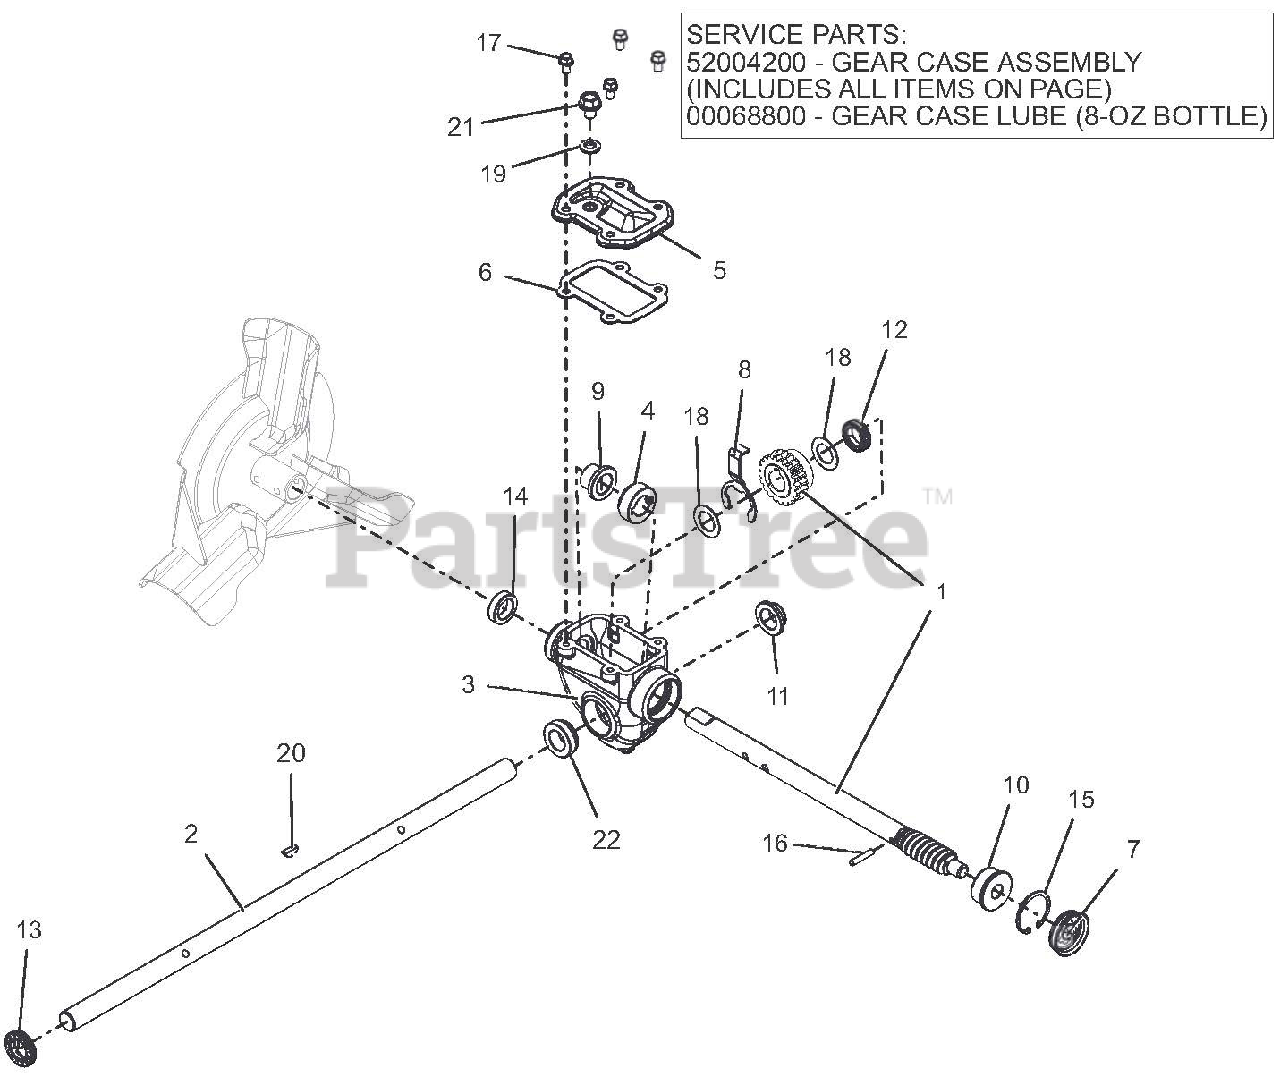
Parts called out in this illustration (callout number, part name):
1	SHAFT AND WORM GEAR ASSEMBLY
2	SHAFT, RAKE - 22" (.750 DIA)
3	GEARCASE, COMPACT MACHINED
4	THRUST COLLAR, .75" ID SLIPFIT
5	COVER, TOP - COMPACT
6	GASKET, TOP - COMPACT GEARCASE
7	COVER, GEAR CASE 1.50"
8	BUSHING RETAINER, COMPACT
9	BSHG-FLG .755X.878X.75X1.25
10	BSHG-FLG .503X1.303X.62X1.465
11	BSHG-FLG .755X.878X.424X1.25
12	SEAL-OIL .748X1.125X.312 TBC29
13	SEAL-OIL .748X1.300X.250 TBC29
14	SEAL-OIL .748X1.125X.312 TB2-H
15	RG-RTNG-INT 1.500X.050
16	PIN-STR .188X1.00 6150
17	BOLT, SEMS .25-20X.50 GR5 YWZC
18	WSHR-FL-STL .760X1.225X.032 YZ
19	WSHR-BND-SEAL .38X.75X.11 GALV
20	KEY-WDRF .19X.63 HRD #61
21	@SCR-ROLOK .38-16X.50 HWH YWZC
22	BSHG-FLG COMPACT, RIGHT
23	GEAR CASE, 22" IRON SM TOP-LD
24	ARIENS L3 LUBE, 8 OZ BOTTLE
